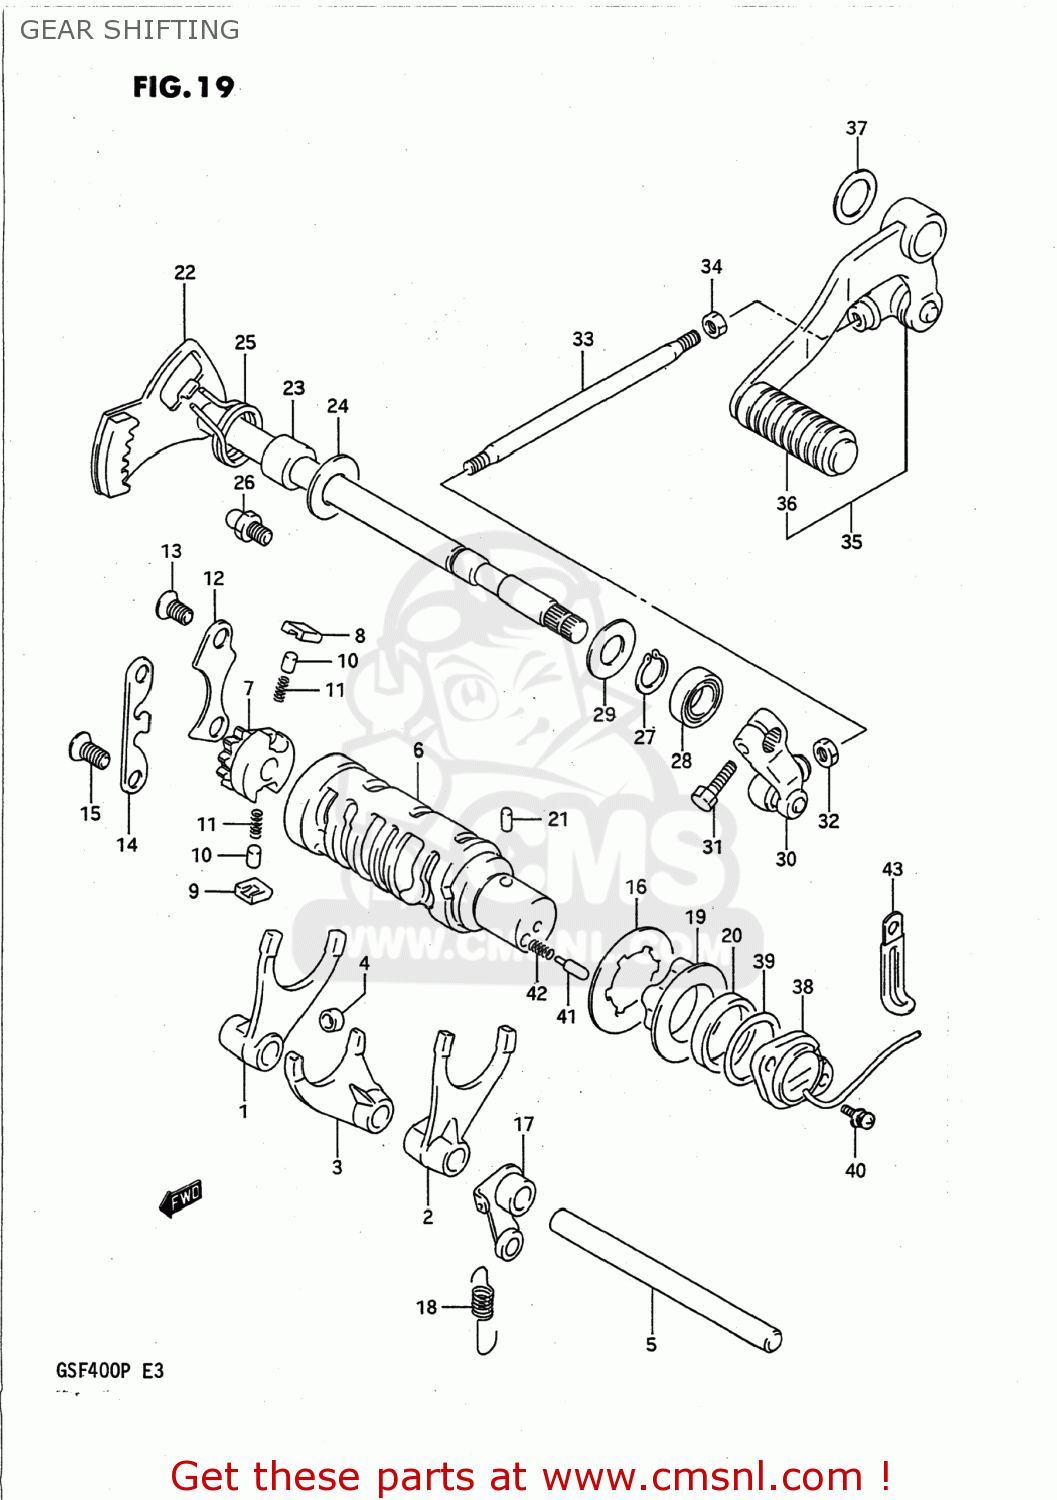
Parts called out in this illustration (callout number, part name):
1	FORK,GEAR SHIFT NO.1
2	FORK,GEAR SHIFT NO.2
3	FORK,GEAR SHIFT NO.3
4	SPACER(6X9.8X6)
5	SHAFT,GEAR SHIFT FORK
6	CAM,GEAR SHIFT
7	GEAR,GEARSHIFT CAM DRIVE
8	PAWL,GEAR SHIFT NO.1
9	PAWL,GEAR SHIFT NO.2
10	PIN(5X8)
11	SPRING
12	LIFTER,GEAR SHIFT PAWL
13	SCREW
14	GUIDE,GEAR SHIFT CAM
15	SCREW
16	WASHER,LOCK
17	STOPPER,GEAR SHIFTING
18	SPRING
19	PLATE,SHIFT CAM STOPPER
20	SPACER (25X30.1X6)
21	PIN 4X6
22	SHAFT,GEAR SHIFT
23	SPACER(12X20X13.8)
24	WASHER
25	SPRING
26	STOPPER,GEAR SHIFT ARM
27	CIRCLIP,12 MM
28	OIL SEAL
29	WASHER (14.2X22X1)
30	ARM,GEAR SHIFT LINK
31	BOLT
32	NUT 6MM
33	ROD,GEAR SHIFT LINK
34	NUT
35	LEVER ASSEMBLY,GEAR SHIFTING
36	RUBBER,GEAR SHIFT PEDAL
37	WASHER(18.2X27X1)
38	BASE ASSY,NEUTRAL SW TERMINAL
39	O-RING (D:2.4 ID:26.2)
40	SCREW
41	PIN(5X15.5)
42	SPRING
43	CLAMP
